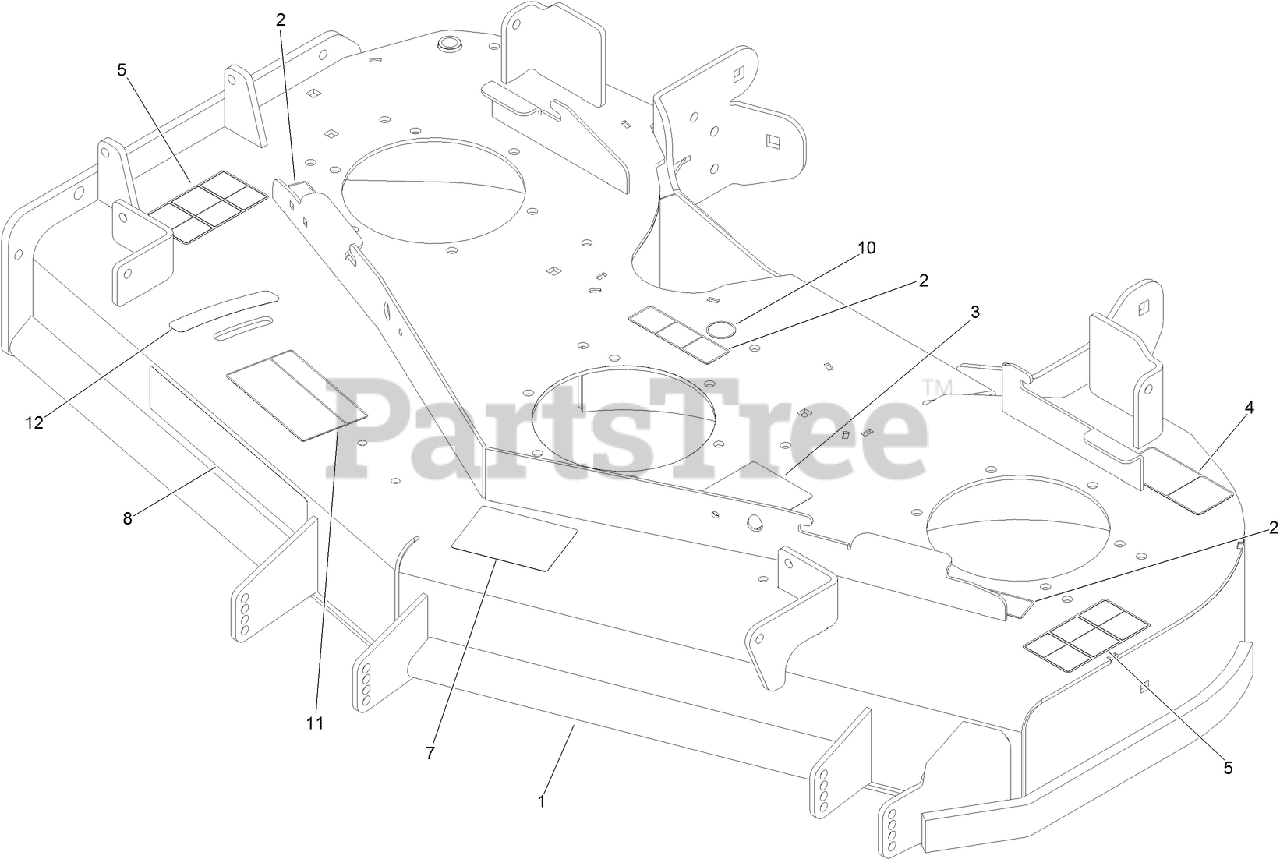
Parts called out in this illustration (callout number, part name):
1	DECK DECAL ASM
2	DECAL-COVER, MISSING
3	DECAL-ROUTING, DECK BELT
4	DECAL-TORQUE, BLADE BOLT
5	DECAL-DANGER
7	DECAL-SCALP, ANTI
10	DECAL-GREASE
11	DECAL-ADJUSTMENT, BAFFLE
12	DECAL-SETTING, BAFFLE
